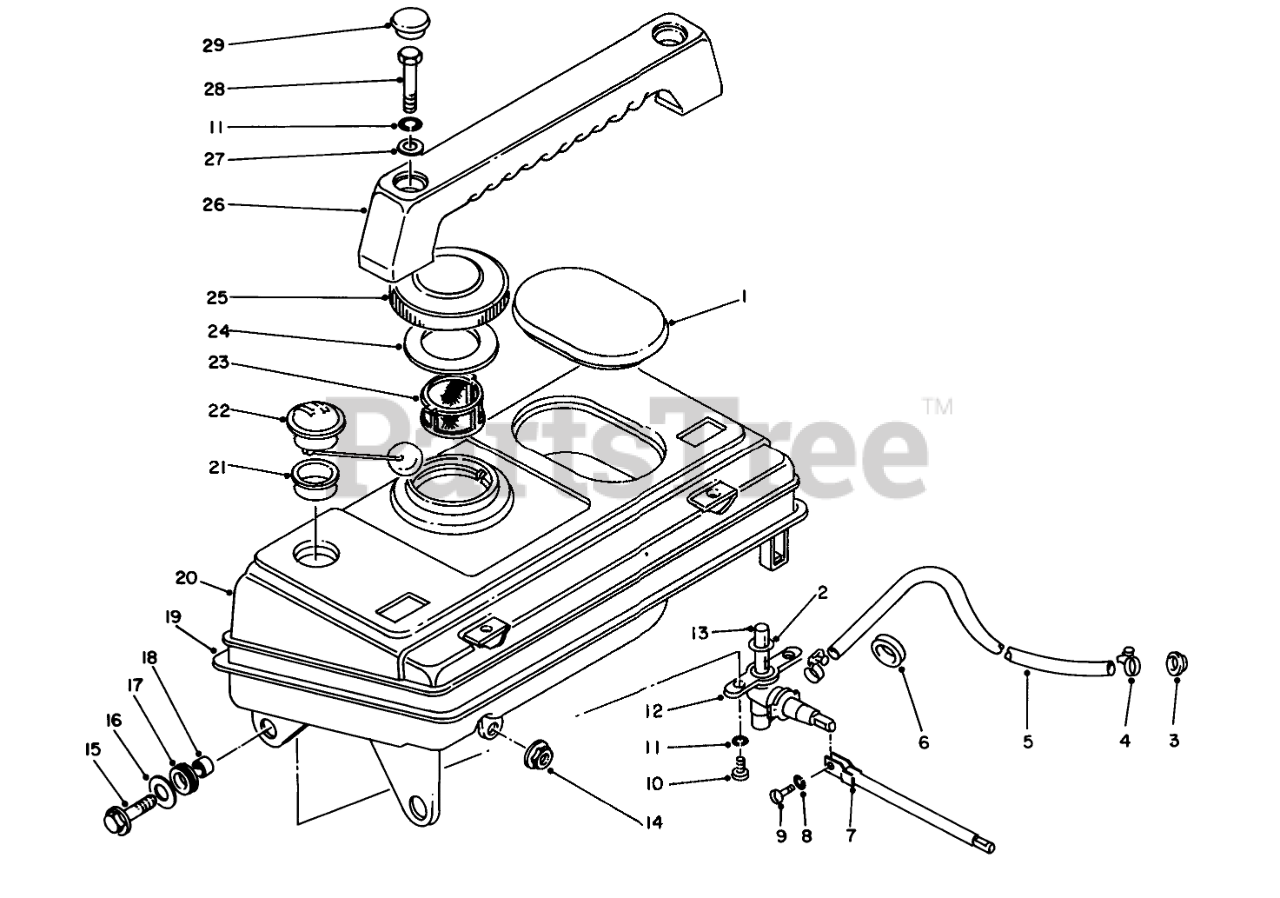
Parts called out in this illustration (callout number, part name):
3	Grommet
5	Hose-Fuel
6	Grommet
8	Lockwasher
9	SCREW
10	Screw
11	Washer-Lock
12	Cock Assembly-Fuel (Incl. Ref. #2 & 13)
16	WASHER
17	CUSHION
18	Spacer
19	Molding
20	Tank Assembly
21	Gasket
22	Gauge Assembly-Fuel (Incl. Ref. #21)
23	FILTER
24	GASKET
27	Washer
